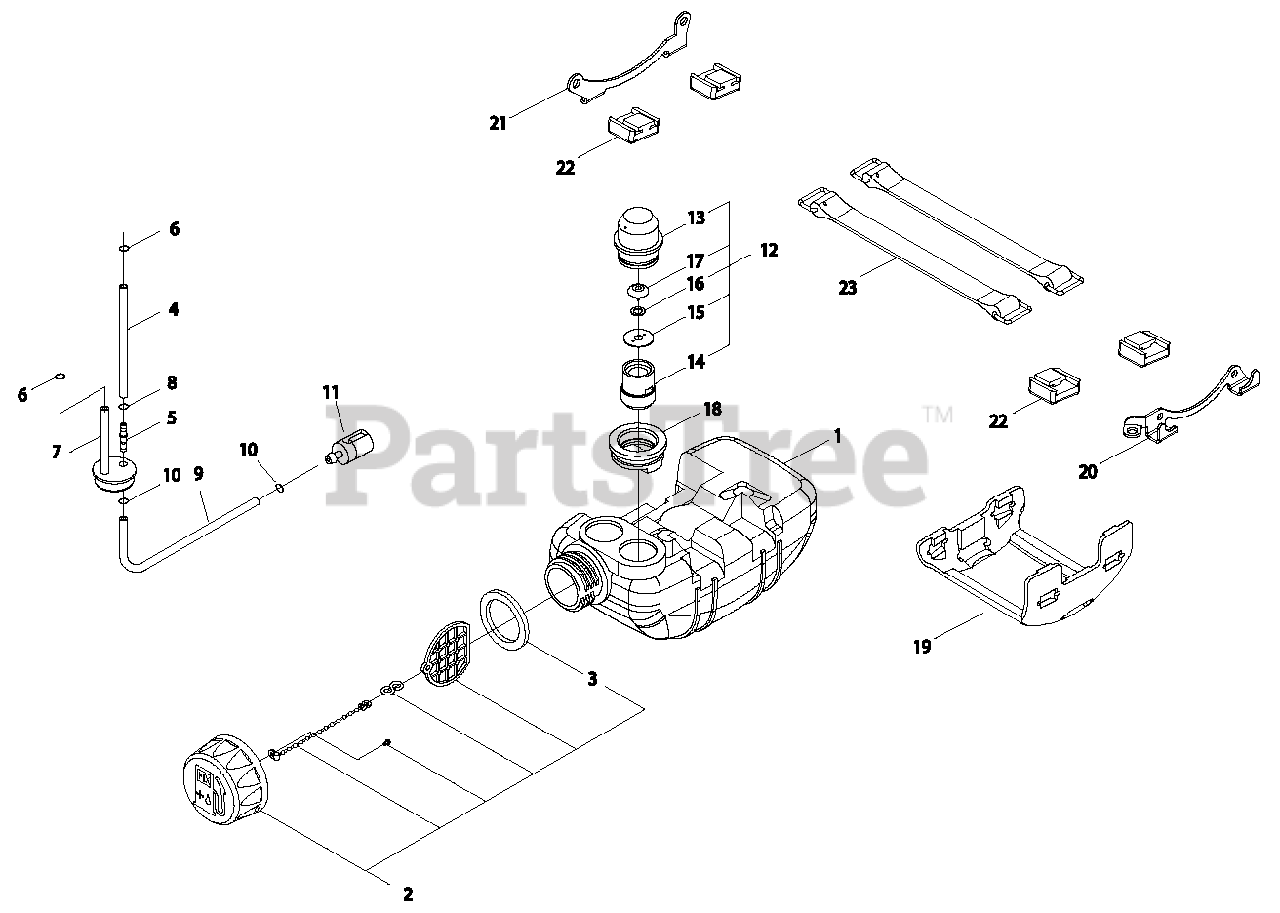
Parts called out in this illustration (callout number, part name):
1	TANK, FUEL
2	CAP ASSY, FUEL
3	GASKET, FUEL CAP
4	PIPE, FUEL
5	CONNECTOR, PIPE
6	CLIP Ø6
7	GROMMET, FUEL W/ PIPE
8	CLIP Ø6
9	PIPE, FUEL
10	CLIP Ø6
11	FILTER ASSY, FUEL
12	VENT ASSY
13	CAP, VENT
14	HOLDER, VENT
15	RETAINER
16	WASHER
17	VENT ASSY
18	GROMMET, VENT
19	GUARD, FUEL TANK
20	BRACKET S
21	BRACKET M
22	CUSHION, FUEL TANK
23	STRAP, FUEL TANK
